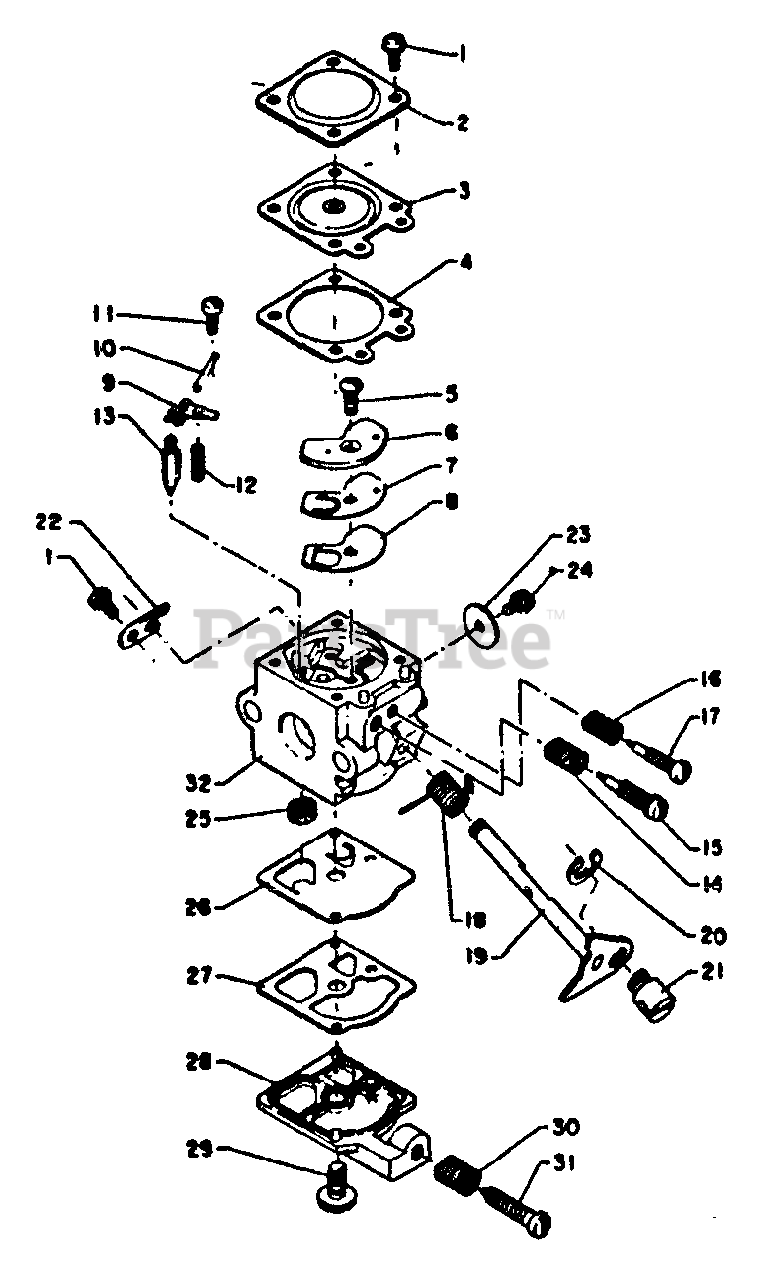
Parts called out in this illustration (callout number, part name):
2	COVER, METERING
3	DIAPHRAGM, METERING
4	GASKET, METERING
5	SCREW, CIRCUIT PLATE
6	PLATE, CIRCUIT
7	VALVE, CHECK
8	GASKET, CIRCUIT PLATE
9	LEVER, METERING
10	PIN, METERING LEVER
11	SCREW, METERING LEVER PIN
12	SPRING, METERING LEVER
13	VALVE, INLET NEEDLE
15	NEEDLE - HIGH SPEED
16	SPRING, IDLE ADJUST
17	NEEDLE - LOW SPEED
18	SPRING, THROTTLE RETURN
19	SHAFT, THROTTLE
20	RING, RETAINING
22	CLIP, THROTTLE SHAFT
23	VALVE, THROTTLE
25	STRAINER
26	DIAPHRAGM, PUMP
27	GASKET, PUMP
28	COVER, PUMP
29	SCREW, PUMP COVER
30	SPRING, IDLE ADJUST
31	SCREW, IDLE ADJUST
32	BODY, CARBURETOR
